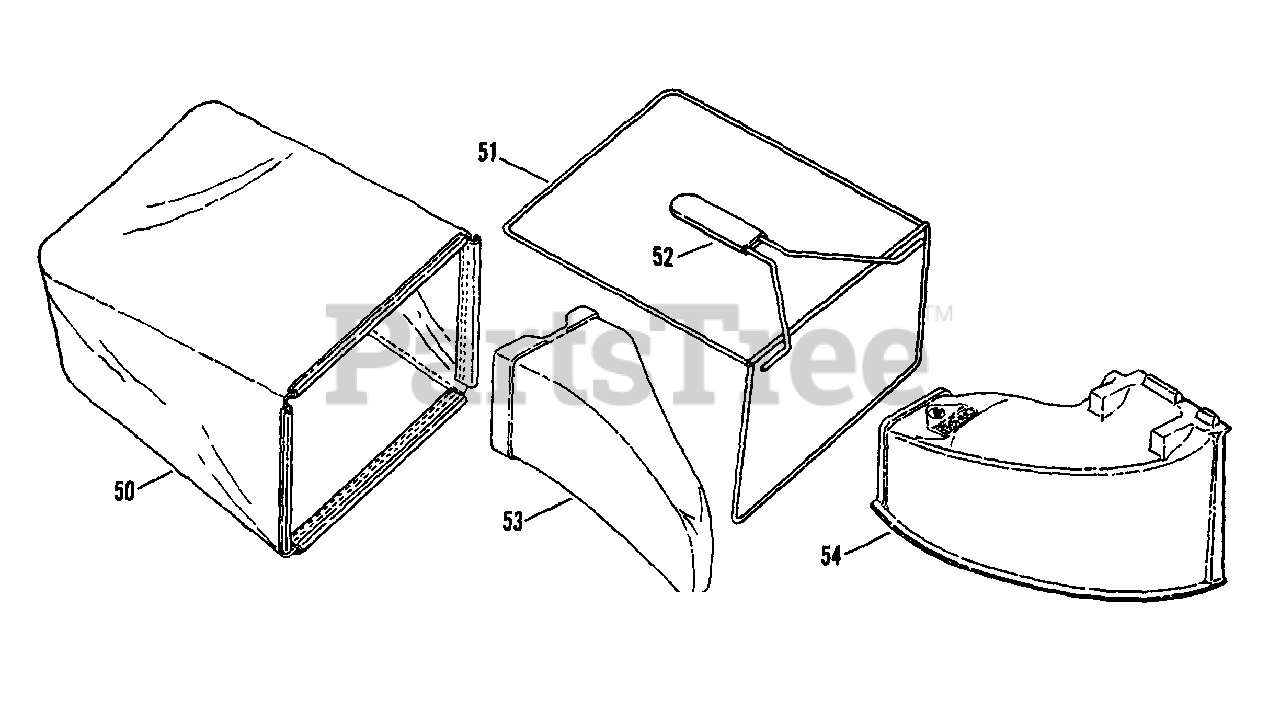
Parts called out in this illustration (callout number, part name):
50	GRASSBAG, SNAPPER Platinum Series
51	ASSEMBLY, Catcher Frame
52	GRIP, Rectangular
53	PLUG, Mulching
54	CHUTE, Side Discharge
